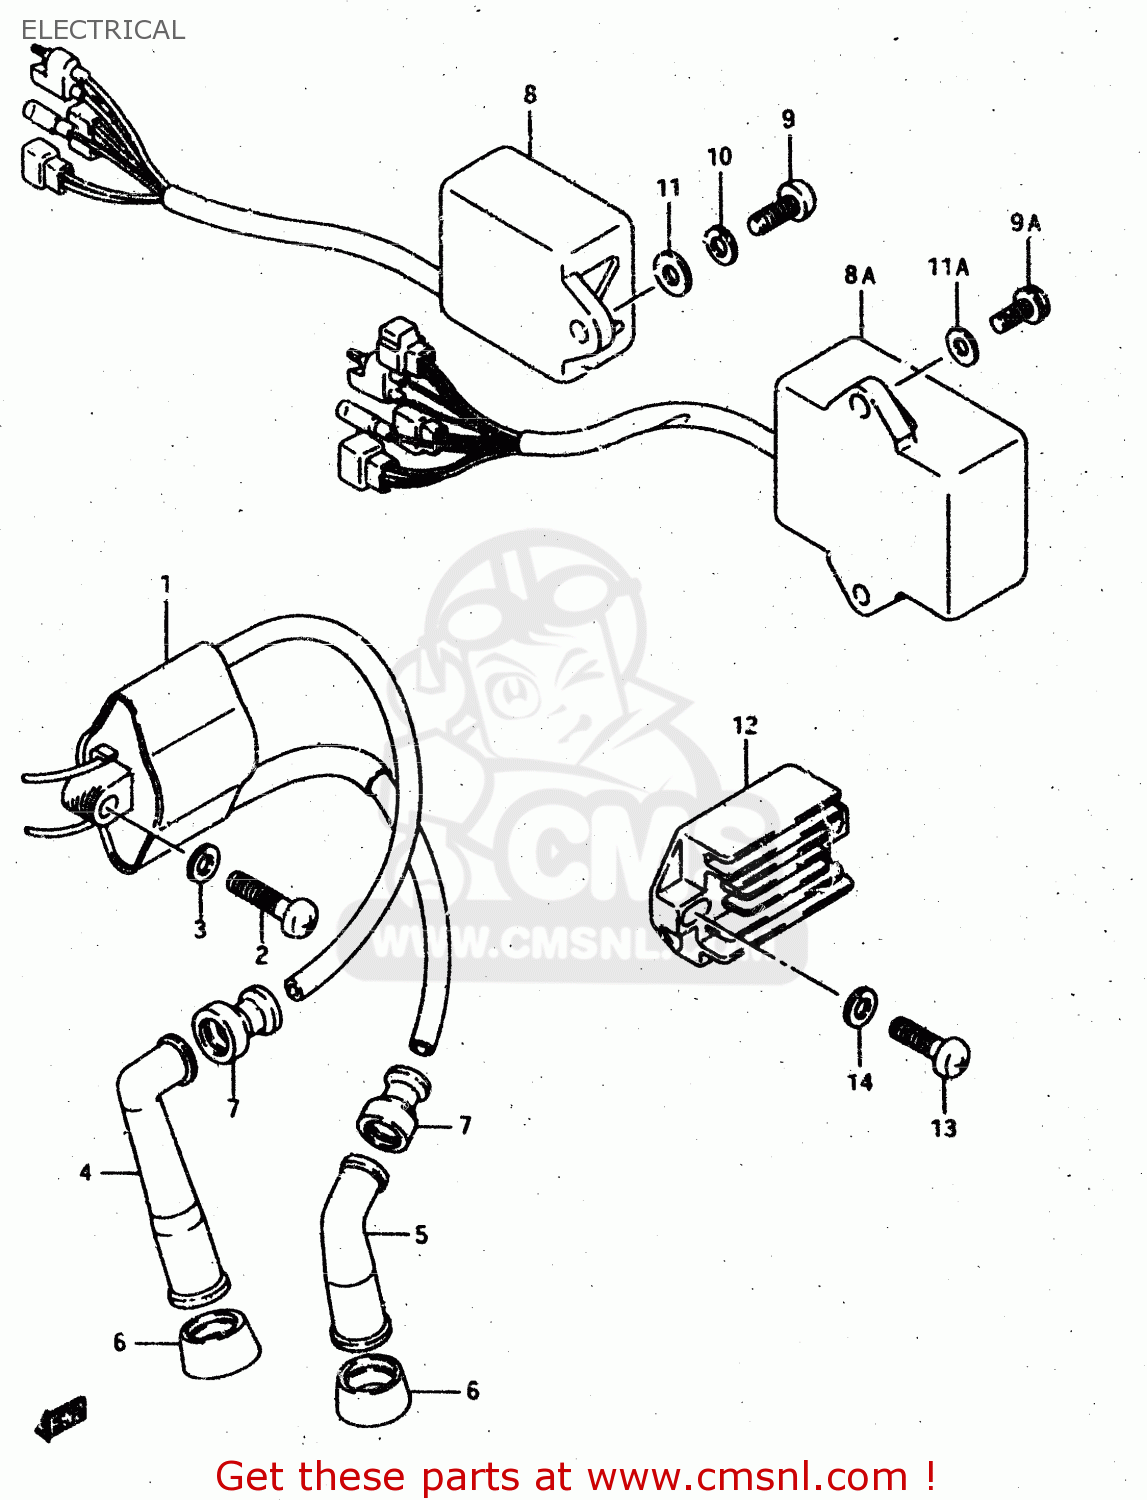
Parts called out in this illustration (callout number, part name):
1	COIL ASSEMBLY,IGNITION
2	SCREW
3	LOCK WASHER
4	CAP ASSY,SPARK PLUG
5	CAP,SPARK PLUG
6	SEAL,SPARK PLUG CAP
7	SEAL,SPARK PLU
8	CDI UNIT
8A	CDI UNIT
9	SCREW
9A	SCREW
10	WASHER,LOCK
11	WASHER, LOWER
11A	WASHER
12	RECTIFIER ASSEMBLY
13	SCREW
14	WASHER,LOCK
